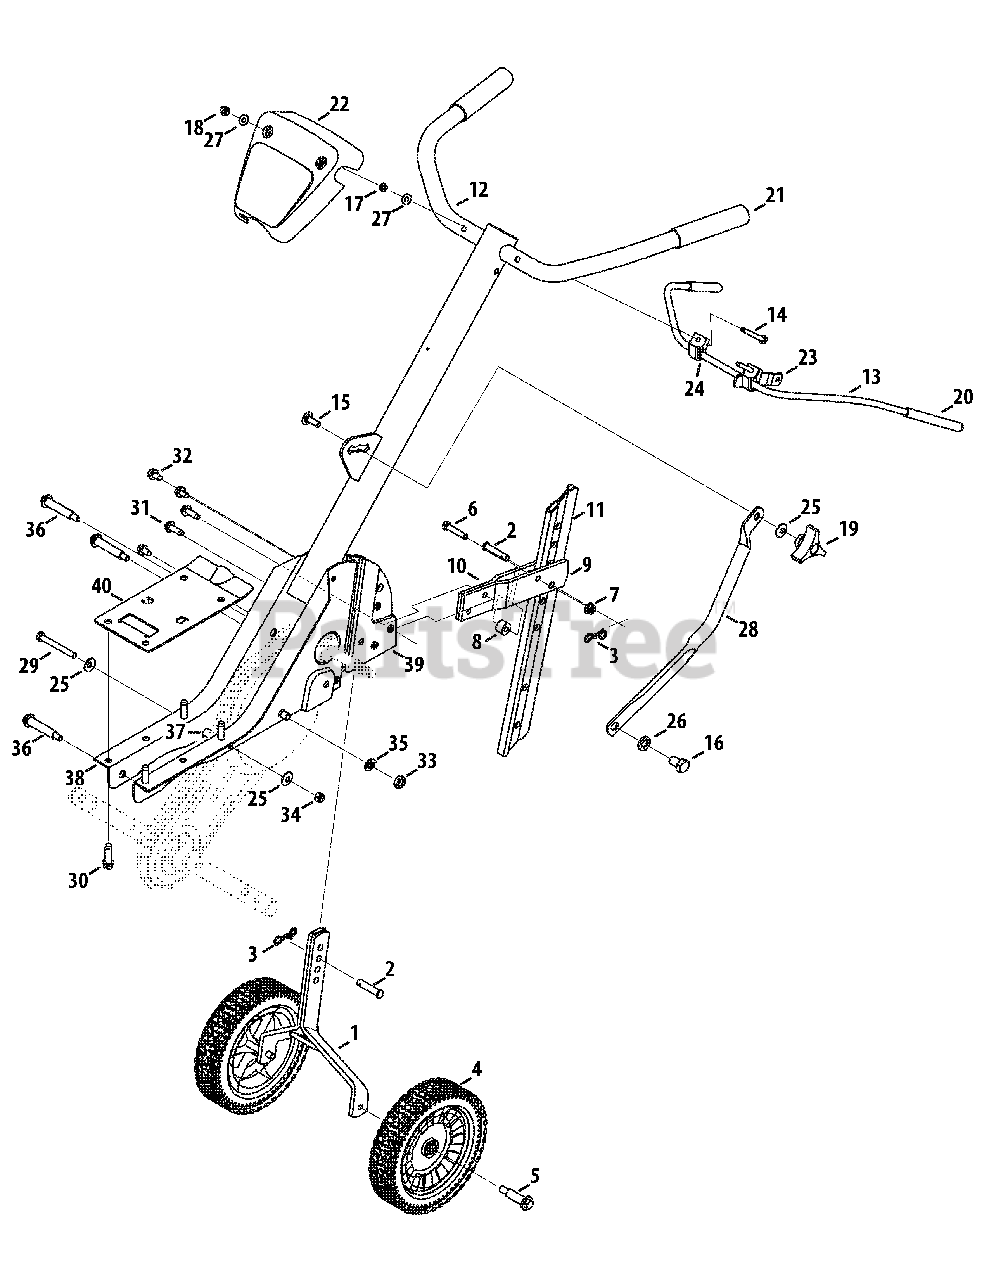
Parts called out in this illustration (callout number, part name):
1	Wheel Bracket Assembly
2	Clevis Pin, .375 x 1.75
3	Bow Tie Cotter Pin
4	Complete Wheel Assy. 8 x 1.75
5	Shoulder Screw, .496 x 1.445 3/8-16
6	Hex Head Screw, 5/16-18 x 1.50
7	Nut, 5/16-18, Flange Lock
8	Spacer, .325 ID x .75 OD x .520
9	Tail Bracket, LH
10	Tail Bracket, RH
11	Depth Bar
12	Complete Handle Assembly
13	Clutch Bail
14	Hex Head Screw, 1/4-20 x 2.25
15	Carriage Screw, 5/16-18 x 1.00
16	Hex Head Screw, 1/2-20 x .750
17	Jam Nut, 1/4-20
18	Nut, 1/4-20, Lock
19	Handle Knob
20	Grip, Clutch Bail
21	Grip, Handle
22	Handle Cover
23	Clutch Bail Holder
24	Flat Washer, .385 x .62 x .063
25	Bell Washer, .340 x .872 x .060
26	Lock Washer, 1/2
27	Flat Washer, .271 x .630 x .065
28	Handle Brace
29	Hex Head Screw, 5/16-18 x 2.75
30	SEMS Screw, 3/8-16
31	Self-Tapping Screw, 5/16-18 x 1.00
32	Self-Tapping Screw, 5/16-18 x .625
33	Jam Nut, 7/16-20
34	Nylon Hex Lock Nut, 5/16-18
35	Lock Washer, 7/16
36	Shoulder Screw, .475 x 2.11 5/16-18
37	Spacer, .47 OD x .96
38	Frame, RH
39	Frame, LH
40	Engine Mounting Plate
